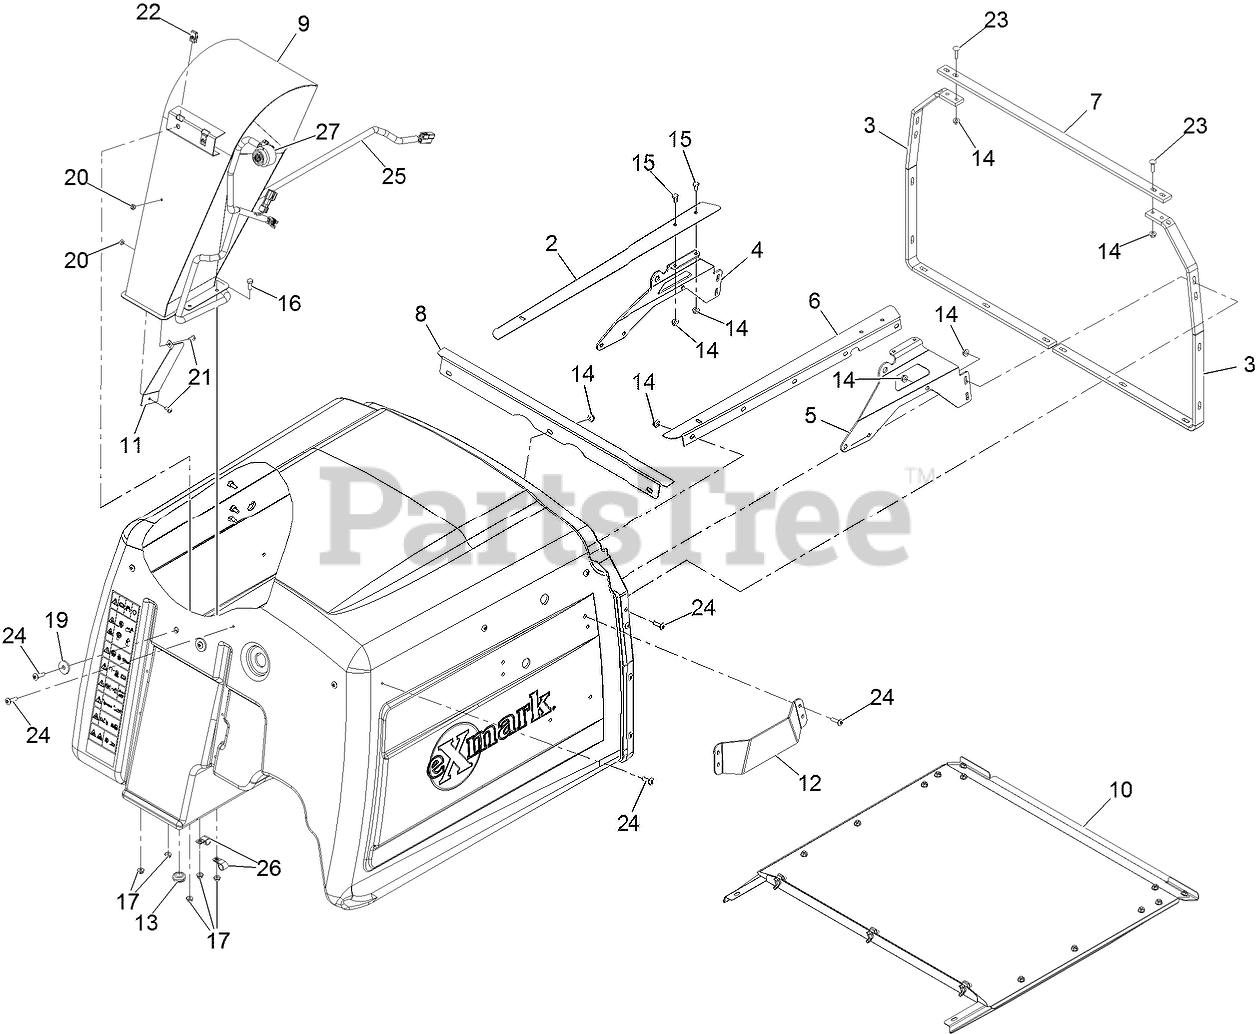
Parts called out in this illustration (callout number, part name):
2	ANGLE-SCREEN TRACK, RH
3	REINFORCEMENT-HOPPER
4	BRACE-DOOR PIVOT, RH
5	BRACE-DOOR PIVOT, LH
6	ANGLE-SCREEN TRACK, LH
7	BRACKET-FRAME CONNECT
8	CHANNEL-SCREEN, FRONT
10	HOPPER SCREEN ASM
11	DEFLECTOR-DISCHARGE CHUTE
12	PLATE-GUARD
13	GROMMET
15	SCREW-HH
16	SCREW-HH
20	NUT-LOCK, NI
21	SCREW-PTH
23	SCREW-CARR
24	SCREW-TTH
25	HARNESS-WIRE, HOPPER
26	CLIP-LOOM
27	ALARM-TONE, DUAL
